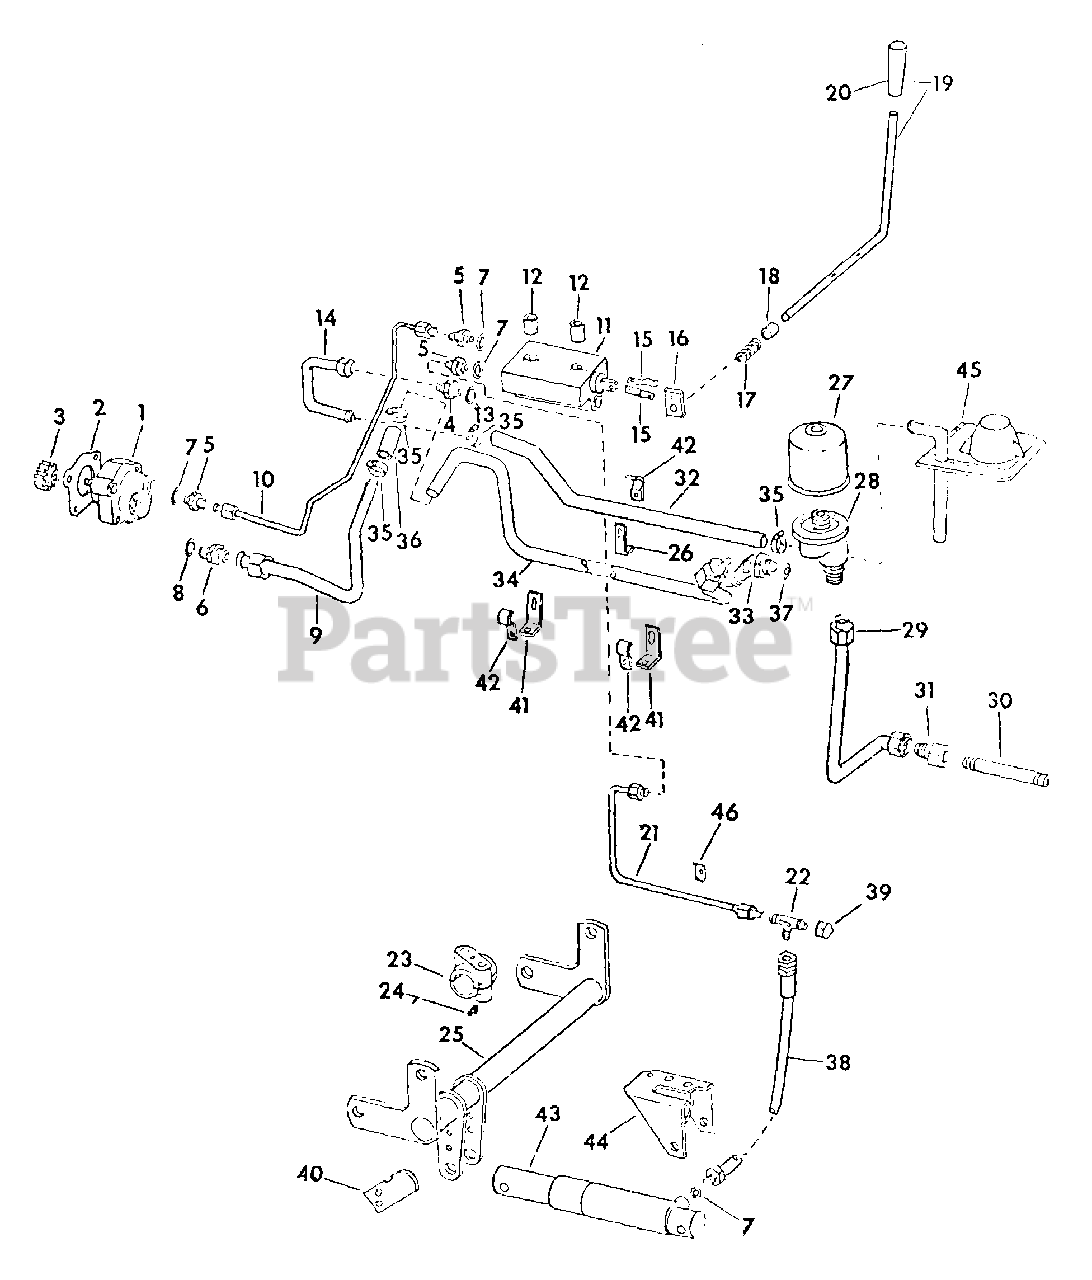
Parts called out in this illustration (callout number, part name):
1	PUMP ASSY, HYDRAULIC (WARNER MOTIVE)
2	GASKET, PUMP
3	GEAR, PUMP DRIVE - 10T
4	CONNECTOR, 3/4-16 37 DEG HYD FLARED TUBE SHORT SWIVEL
5	CONNECTOR, 9/16-18 37 DEG HYD FLARED TUBE SHORT SWIVEL
6	UNION, 7/8-14 C-Z 37 DEG HYD FLARED TUBE SHORT SWIVEL
7	O-RING, 3/8 OD TUBE
8	O-RING, 3/4 X 15/16 X 3/32
9	TUBE ASSY, SUCTION SHORT
10	TUBE ASSY, PRESSURE LONG
11	VALVE ASSY, CONTROL
12	SPACER, VALVE
13	O-RING, 1/2 OD TUBE
14	TUBE ASSY, RETURN
15	BAR, HYDRAULIC VALVE OPERATING
16	LEVER, VALVE HANDLE
18	SPACER, HANDLE
19	HANDLE ASSY, VALVE
20	GRIP, HANDLE
21	TUBE ASSY, HYDRAULIC CYLINDER
22	TEE, 9/16-18 37 DEG HYD FLARED TUBE THREE WAY
23	BEARING ASSY, ROCKSHAFT
24	FITTING, 3/16 65 DEG ANGLE DRIVE TYPE LUB
25	ROCKSHAFT ASSY
26	SUPPORT, TUBE CLAMP
27	FILTER ASSY, HYD OIL-SPIN-ON
28	BASE, HYD OIL FILTER
29	TUBE ASSY, HYD FILTER SUCTION
30	NIPPLE, 1/2 X 5-1/2 PIPE
31	CONNECTOR, HYDRAULIC FLARED TUBE
32	HOSE, RETURN
33	ELBOW, 1-1/16-12 C-Z 37 DEG HYD FLARED TUBE ADJ 45 DEG
34	TUBE ASSY, SUCTION LONG
35	CLAMP, RETURN HOSE
36	HOSE, SUCTION TUBE
37	O-RING, 3/4 OD TUBE
38	HOSE ASSY, HYDRAULIC
39	CAP, 9/16-18 37 DEG HYD FLARED TUBE
40	BAR, ROCKSHAFT STOP
41	SUPPORT, TUBE CLAMP
42	CLAMP, HYDRAULIC TUBES
43	CYLINDER ASSY, HYD 1-3/4 X 5
44	BRACKET ASSY, CYL MTG
45	HOUSING ASSY, GEAR SHIFT LEVER
46	CLAMP, HYD TUBES
